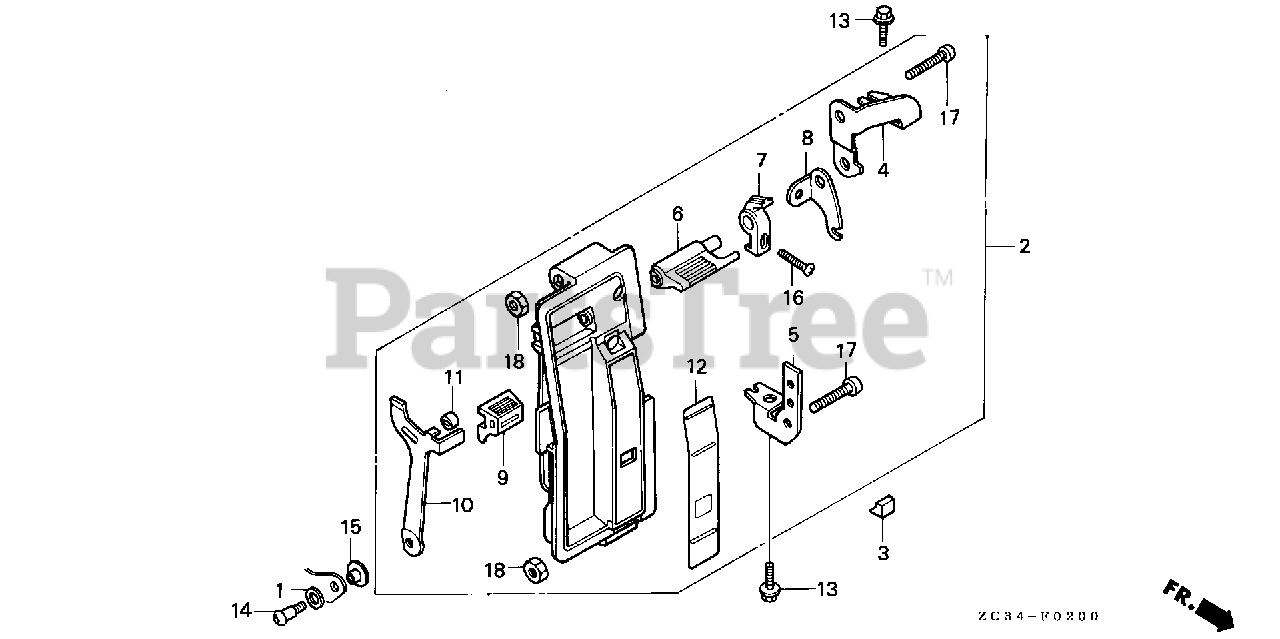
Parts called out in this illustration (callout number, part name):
1	WASHER, AIR CLEANER COVER SETTING
2	CONTROL ASSY., SWITCH
3	BUSH, SWITCH GUIDE
4	BRACKET, SWITCH GUIDE
5	BRACKET, ENGINE SWITCH
6	KNOB, POWER CHANGE
7	ARM A, POWER CHANGE
8	ARM B, POWER CHANGE
9	KNOB, ENGINE SWITCH
10	LEVER, CONTROL
11	PIN, CONTROL LEVER GUIDE
12	MARK, ENGINE SWITCH
13	BOLT, FLANGE (5X10)
14	SCREW, PAN (4X10)
15	COLLAR (6MM)
16	SCREW, PAN (4X18)
17	SCREW, PAN (5X25)
18	NUT, HEX. (5MM)
